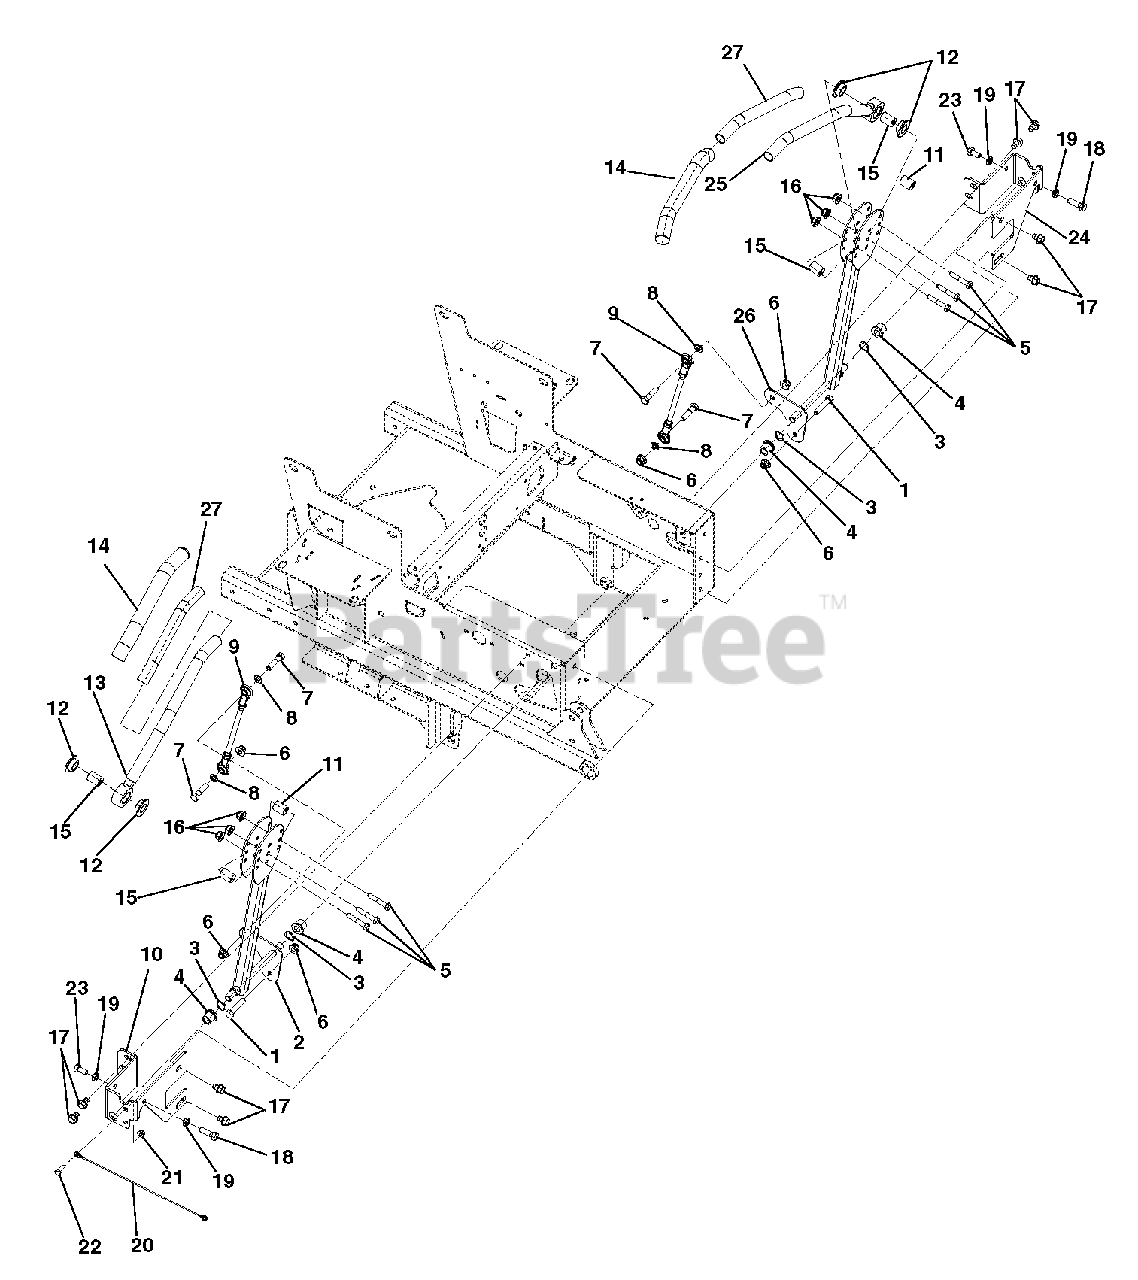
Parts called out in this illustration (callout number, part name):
1	Bolt, Hex .38-16 x 2.00 Full Thread
2	Weldment, Right Hand Control
3	Wave Washer .640 x .875 x .125 Free Height
4	Bushing, Flange .515 x .750 x .745 x 1.00 Nylon
5	Bolt, Hex .31-18 x 1.75 Grade 5
6	Nut, .38-16 Nyloc Flange
7	Bolt, Hex .38-16 x 1.50 Grade 5
8	Washer, Locking .38 x .094 Regular
9	Assembly, Steering Linkage
10	Bracket, Right Hand Steering Stop
11	Eccentric
12	Bushing, Flange .762 x 1.48 x .44 Nylon
13	Handle Weldment Right Hand
14	Grip, Handlebar
15	Spacer, .328 x .76 x 1.01
16	Nut, .31-18 Nyloc Flange
17	Screw, Tapping .38-16 x .50 Hex Washer Head Thread Rolling
18	Bolt, Hex .38-16 x 1.25 Grade 5
19	Nut, Hex-Jam .375-16
20	Cable, 12.0 Lanyard, Nylon
21	Nut, .25-20 Nyloc Flange
22	Bolt, Hex .25-20 x .75 Grade 5
23	Bolt, Hex .38-16 x .75 Grade 5
24	Bracket, Left Hand Steering Stop
25	Weldment, Handle Left Hand
26	Weldment, Left Hand Control
